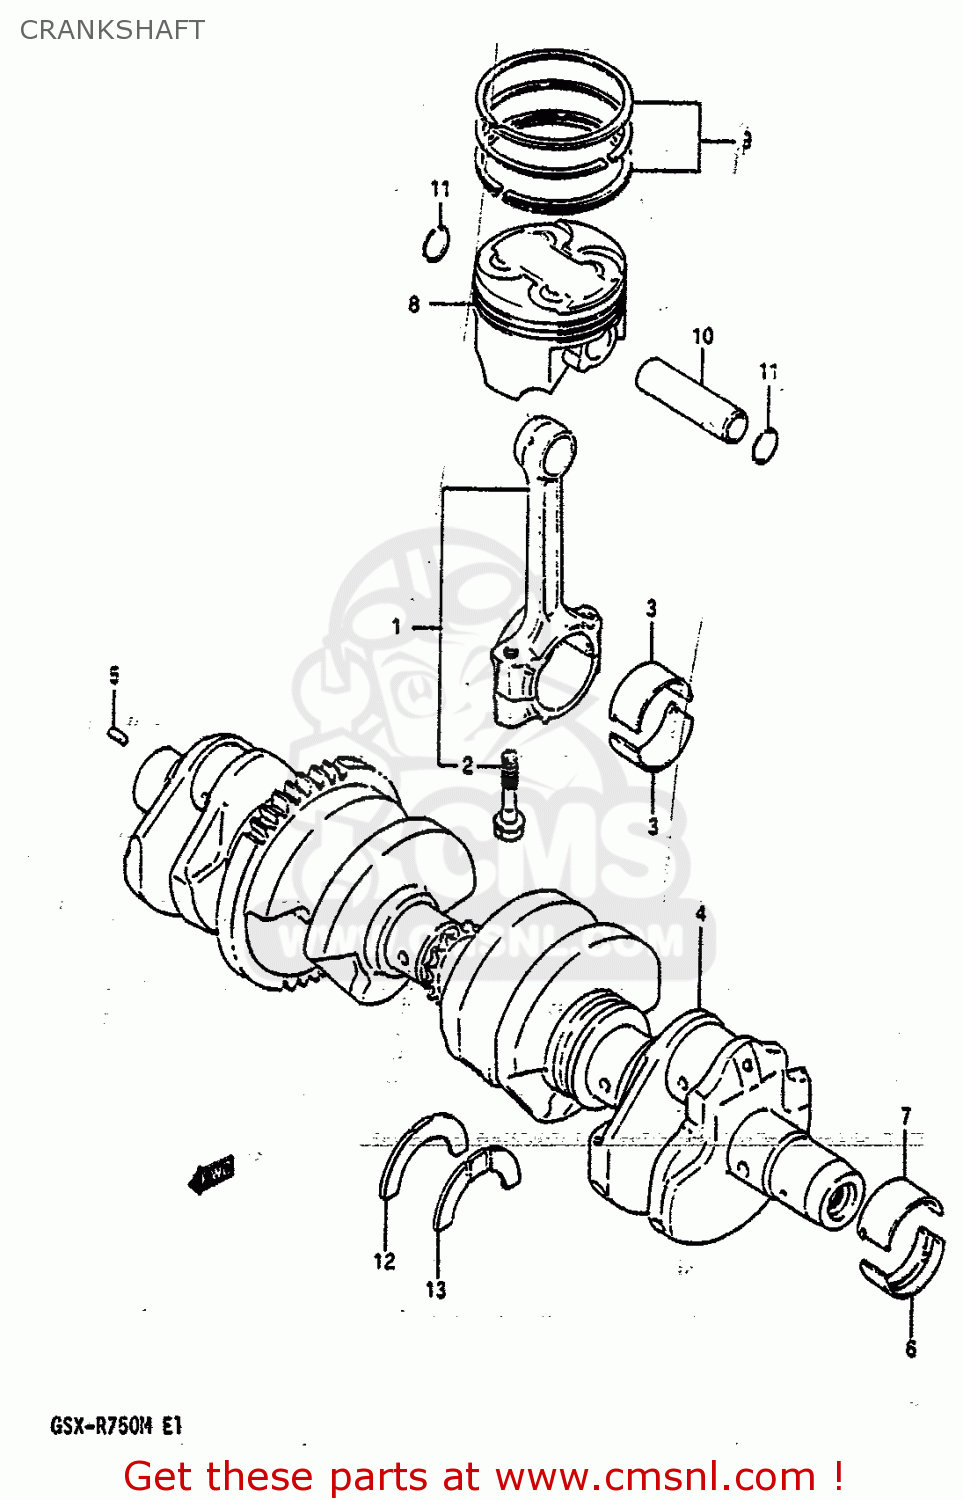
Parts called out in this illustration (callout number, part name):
1	ROD ASSEMBLY,CONNECTING
2	BOLT,CONNECTING ROD
3	BEARING,CRANK PIN
4	CRANKSHAFT
5	PIN
6	BEARING,CRANKSHAFT LWR
7	BEARING,CRANKSHAFT UPR
8	PISTON
9	RING SET,PISTON
10	PIN,PISTON
11	CIRCLIP
12	PLATE,CRANK THRUST
13	PLATE,CRANK THRUST
